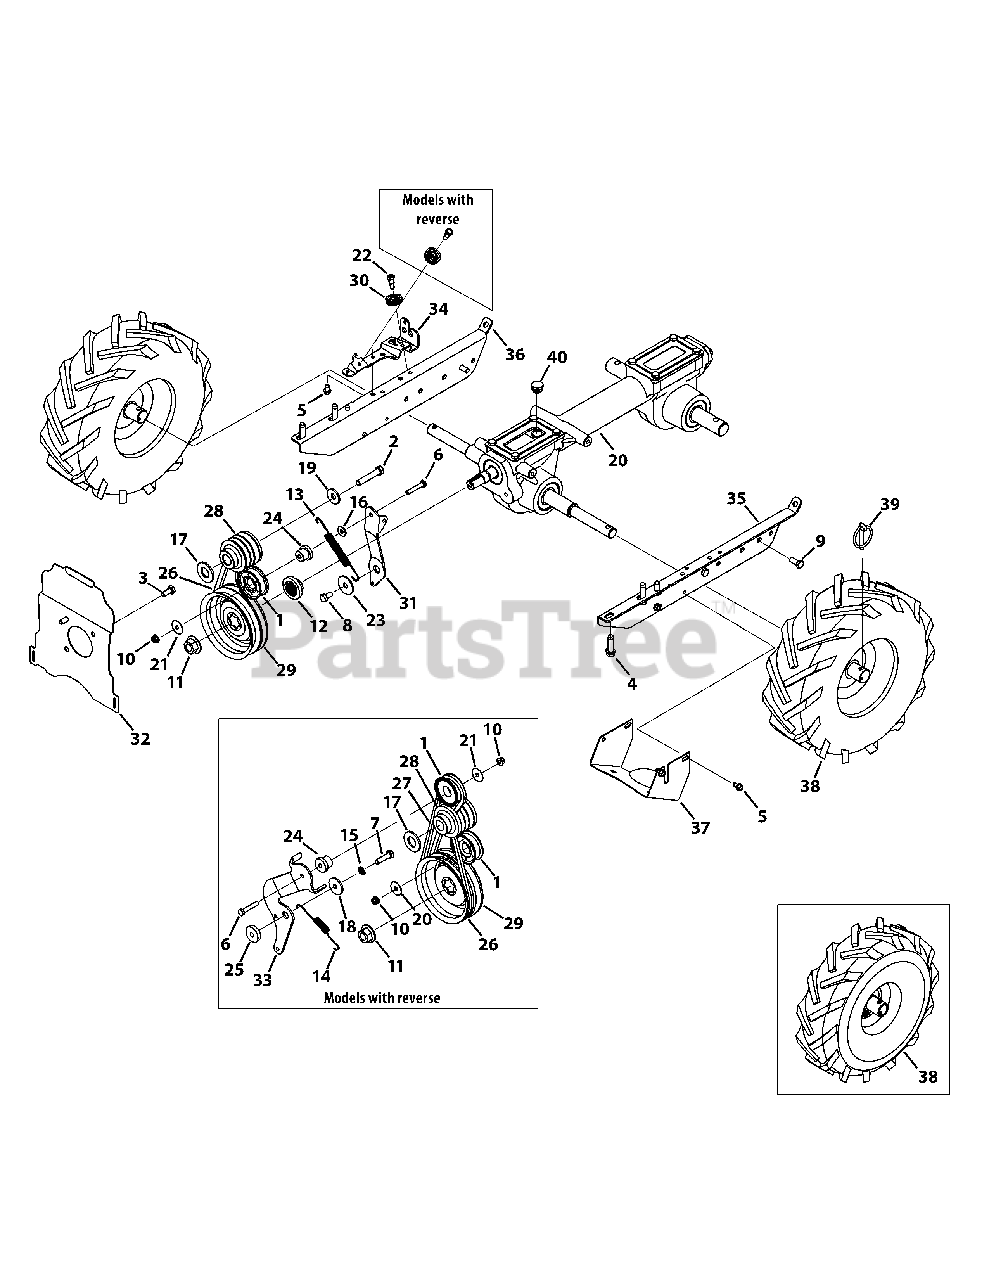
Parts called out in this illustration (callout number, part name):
1	Idler Pulley Assembly, 1.917 OD
2	Hex Head Screw, 3/8-24 x 2.00
3	Hex Head Screw, 5/16-24 x .625
4	Screw, 3/8-16 x 1.250
5	Screw, 1/4-20 x 0.500
6	Hex Head Screw, 1/4-20 x 1.50
7	Hex Head Screw, 5/16-24 x 1.25
8	Hex Head Screw, 5/16-18 x .75, Patch
9	Hex Head Screw, 5/16-18 x .75, Std.
10	Flangelock Nut, 1/4-20
11	Flange Nut, 9/16-18
12	Pulley Hub, 5/8 SPLINE
13	Extension Spring, .480 OD x 5.00 LG
14	Extension Spring, LT5 PTO
15	Washer, Lock, 5/16
16	Washer, Flat, .28 x .74 x .063
17	Washer, Flat, .760 x 1.50 x .120
18	Washer, Flat, .330 x 1.25 x .120
19	Washer, Bell, .396 x 1.140 x .095
20	Transmission Assembly 2/23/09 & Before
20	Transmission Assembly 2/23/09 & After
21	Washer, Flat, .265 x 1.0 x .030
22	Screw, Shoulder, 1/4-28 x .340 x .335
23	Forward Idler Pivot Spacer
24	Spacer, Shoulder, .260 x .785 x .538
25	Reverse Idler Pivot Spacer
26	V Belt, 4L x 25.375 LG
27	V Belt, 3L x 29.125 LG
28	Engine Pulley, 3L & 4L
29	Transmission Pulley
30	Cable Roller
31	Forward Idler Bracket
32	Cover Mounting Plate
33	Reverse Idler Bracket
34	Pulley Mounting Bracket
35	LH Mount Frame
36	RH Mount Frame
37	Pulley Shield
38	Wheel, 13 x 5 x 6
38	Wheel Assembly, 11 x 4-4
39	Klik Pin, .25 DIA x 1.56
